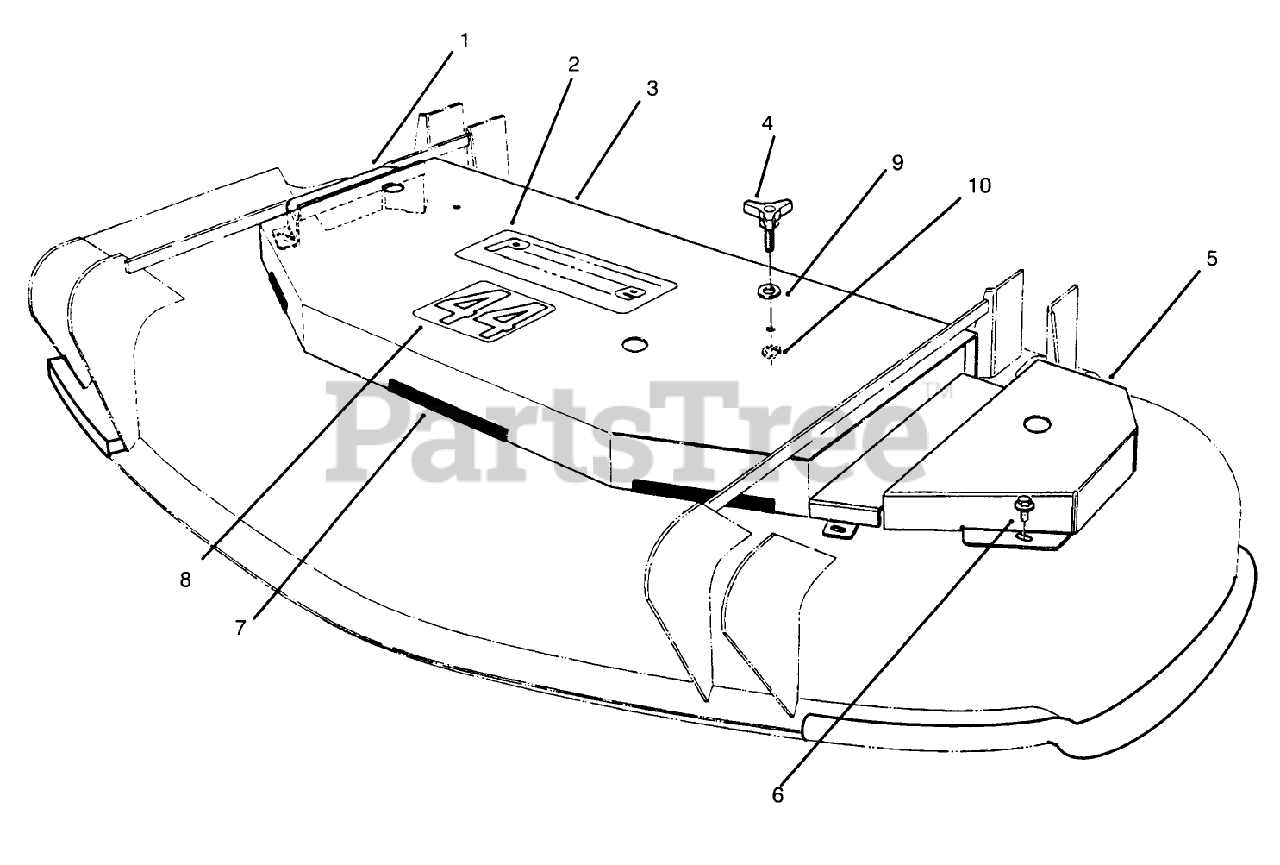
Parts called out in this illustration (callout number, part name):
1	Cover-RH
2	DECAL-PROLINE
3	Cover-Deck
5	Cover-LH
6	SCREW-HHFTF
7	TRIM-JIFFY
8	DECAL-44 INCH
9	WASHER-FLAT
10	RING-RETAINING
